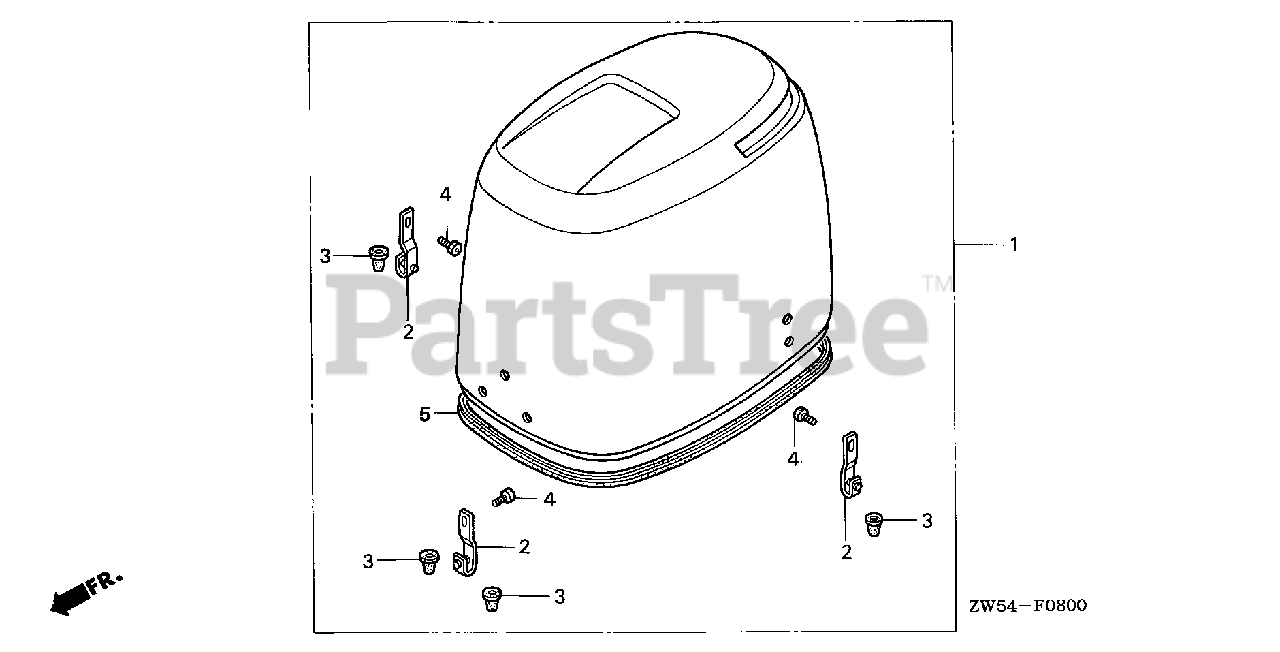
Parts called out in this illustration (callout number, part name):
1	COVER ASSY., ENGINE *NH282MU* (OYSTER SILVER METALLIC-U)
2	HOOK, ENGINE COVER
3	DAMPER, HOOK
4	BOLT, SOCKET (8X16)
5	SEAL, ENGINE COVER
